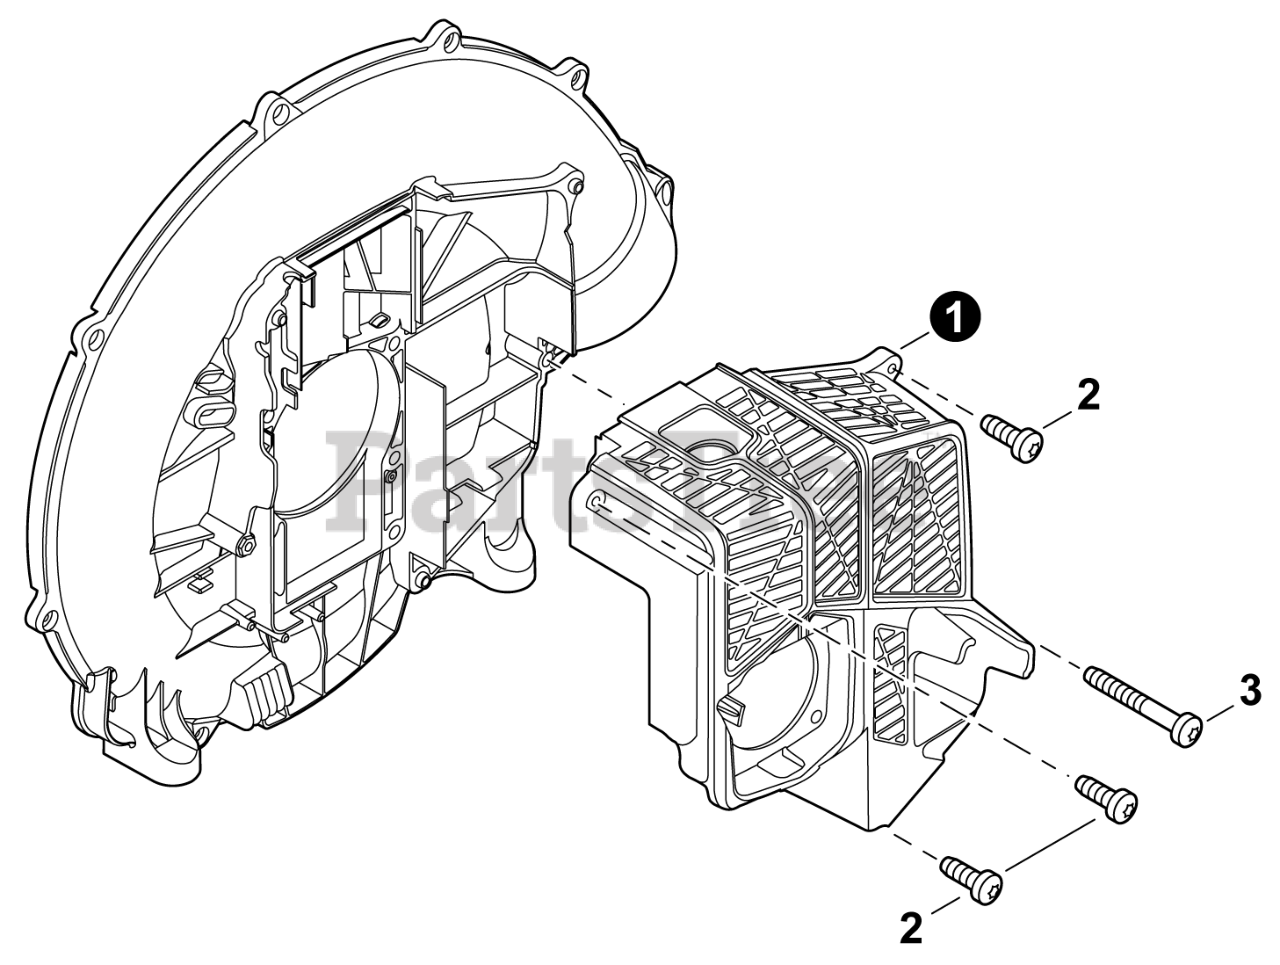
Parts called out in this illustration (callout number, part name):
1	COVER, ENGINE
2	BOLT, TORX 5x20
3	BOLT, TORX 5x55
